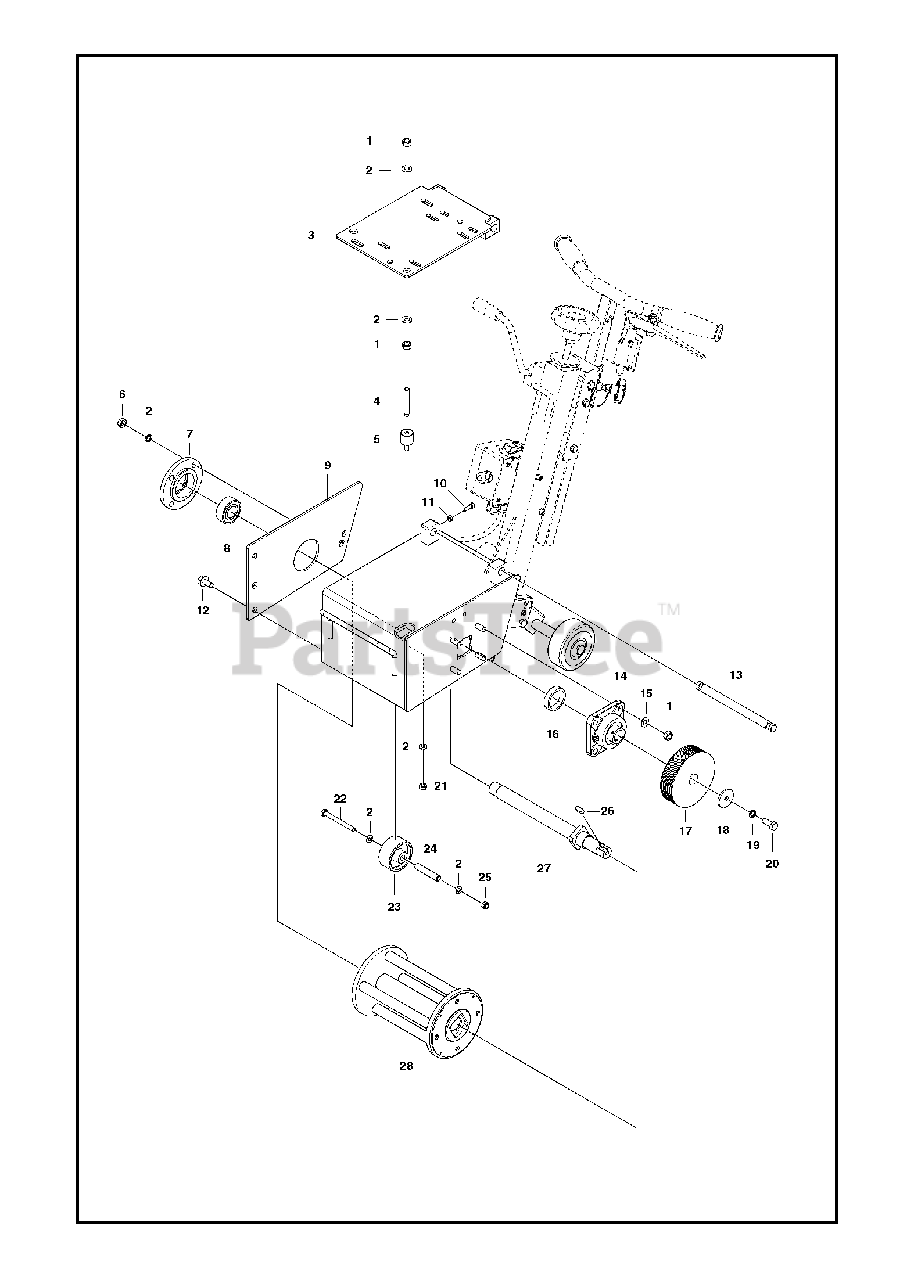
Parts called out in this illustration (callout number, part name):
2	WASHER
10	SCREW IHSCM
15	WASHER
21	HEXAGON NUT
25	HEXAGON LOCKING NUT
